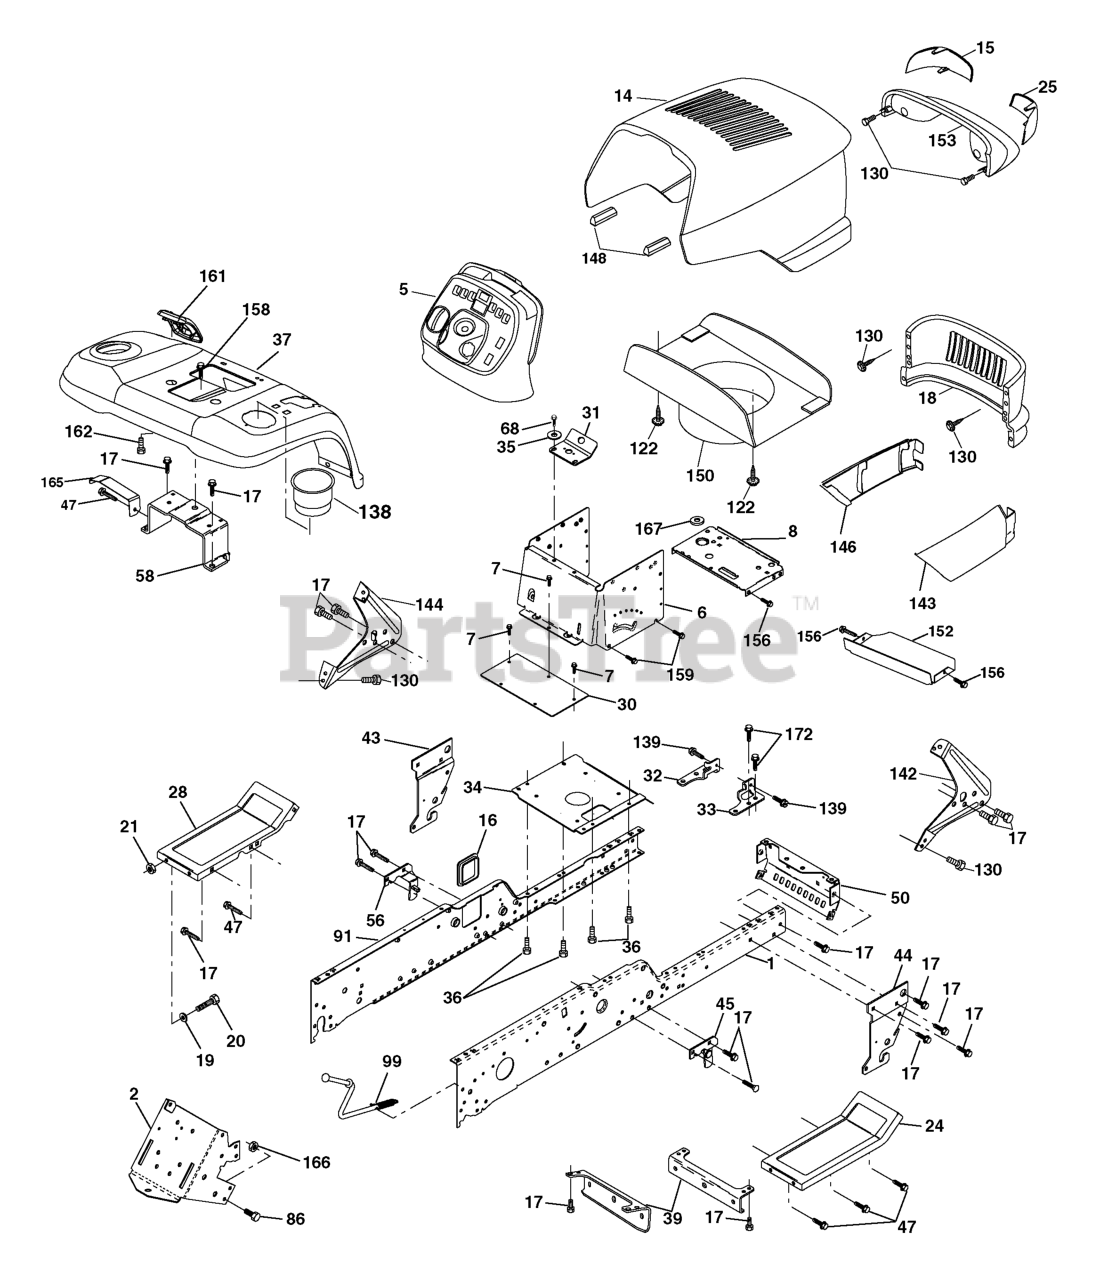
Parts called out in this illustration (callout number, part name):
1	KIT.RAIL.CHASS.RH.GT
2	DRAWBAR, GT
5	DASH.PANEL.GREY
6	DASH VGT, LOWER
7	SCREW
8	SUPPORT, BATTERY
14	HOOD
15	LENS LH
16	COVER ACCESS
17	SCREW, 3/8-16X3/4
18	GRILLE.STEALTH P/L.YTGT.GREY
19	WASHER
20	BOLT
21	NUT
24	FOOTREST PNT RH
25	LENS RH
28	FOOTREST PNT LH
30	SADDLE.HYDRO.95
31	BRACKET SUPT 1-PC VGT STEERING
34	PLATE ASM ENG CHASSIS
35	WASHER
36	SCREW 5/16"
37	KIT.FENDER.YTGT.W/S
39	BRACKET AXLE, FRONT
43	FRONT SUSPENSION BRKT LH
44	FRONT SUSPENSION BRKT RH
45	BRACKET, ASM., SUSP CHASSIS RH
47	SCREW LT
50	BRACKET, CHASSIS FRONT
56	BRACKET ASM., SUSP CHASSIS LH
58	BRACKET ASM., FENDER
68	Screw, 5/16-18 x 1/2
86	BOLT FIN HEX 7/16-14 X 1
91	KIT.RAIL.CHASS.LH.GT
99	ROD ASM, BYPASS
122	SCREW.WSHD.HEX10-32X5/8
130	SCREW
138	CUPHOLDER.YTGT
139	BOLT, SHOULDER 5/16-18
142	BRACKET DASH STEALTH(R)
143	SKIRT GRILLE RH
144	BRACKET DASH STEALTH LH
146	SKIRT GRILLE LH
148	EXTRUSION BUMPER (3 2) (2 2)
150	DUCT.HEAT.HOOD.STEALTH.GT
152	BROWNING SHIELD
153	LIGHTBOX.ASM.STV.DL.INC.HUSQ
156	SCREW
158	SCREW 3/8-16X1/2
159	SCREW, 3/8-16X3/4
161	CONSOL.FUEL.WINDOW.BLACK
162	SCREW.HI-LO.CONSOLE
165	BRACKET SUPPORT TANK
166	Nut, Lock Hex 7/16-14 unc
167	BUSHING SNAP
172	SCREW 3/8-16X.875
